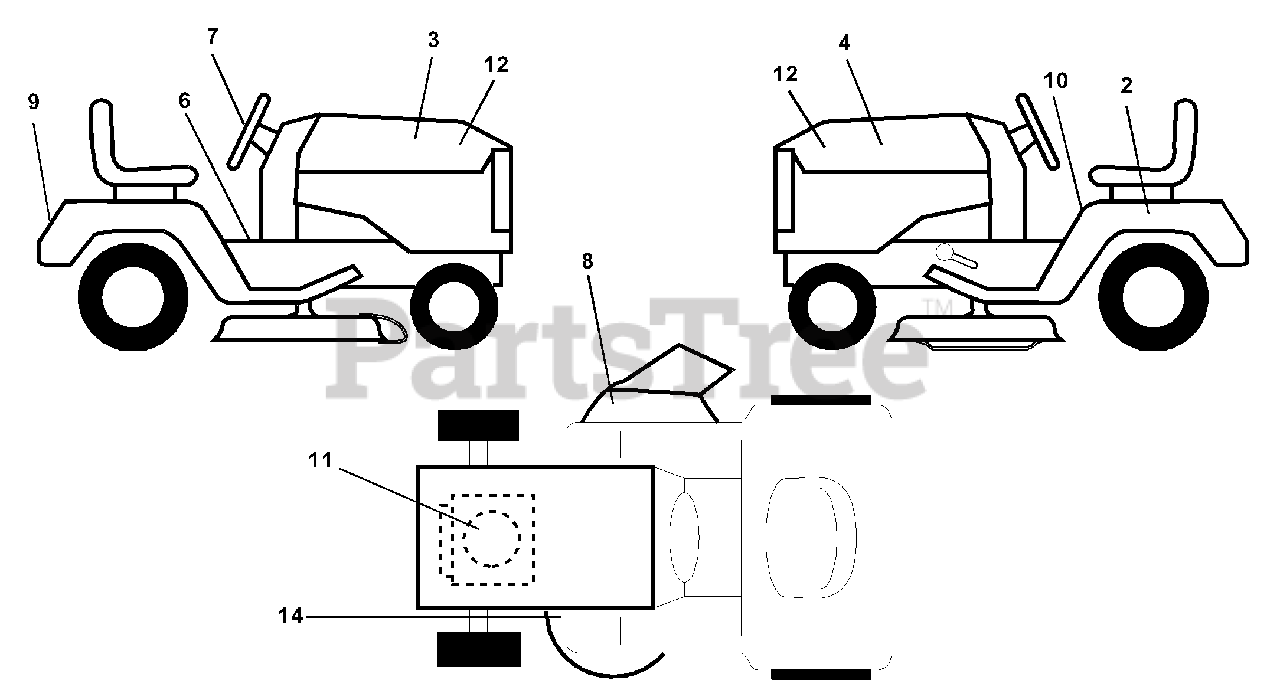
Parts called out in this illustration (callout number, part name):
2	Decal Battery
3	Decal Hood RH
4	Decal Hood LH
6	Decal Fender Oper
7	Decal Wheel Steering
8	Decal Warning
9	Decal Fender Husq
10	Decal Fender Danger E/F
11	Decal Engine
12	Decal Hood
14	Decal V-Belt Schematic
